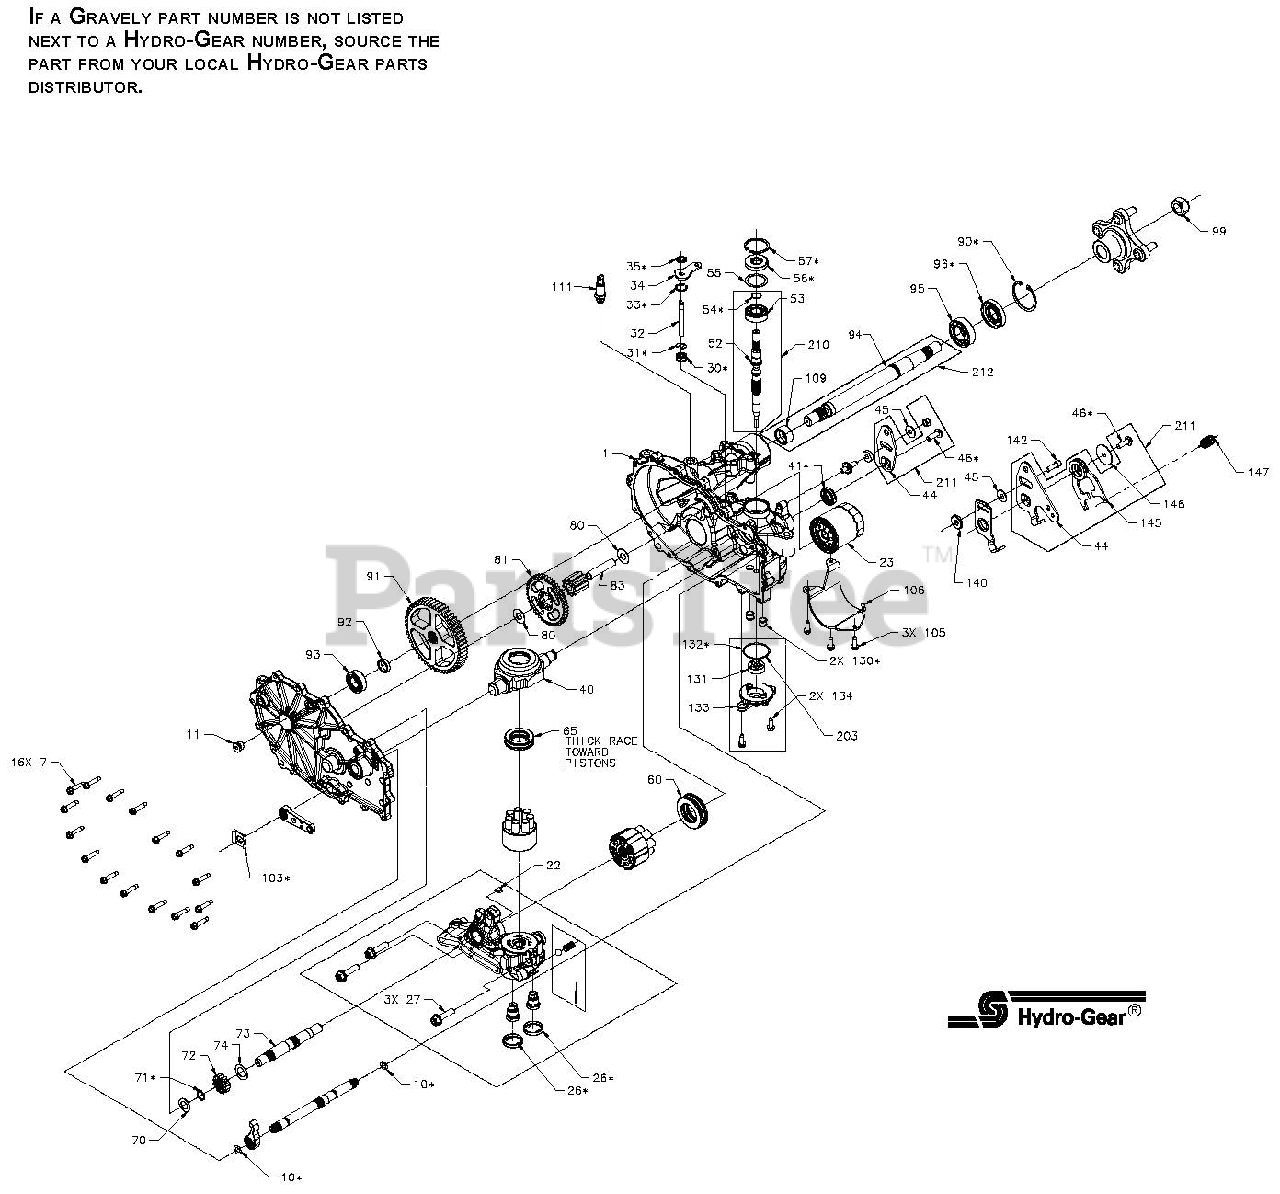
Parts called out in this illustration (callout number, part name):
1	Kit, Main Housing LH
7	HFHCS 1/4-20 x 1.25
10	O-Ring, 111 .103 x .424
11	Plug, 9/16-18
22	Plate, Bypass
23	Filter, Oil
26	Seal, Plug 1.25 x .25
27	HFHCS, 3/8-16 x 1.5
30	Seal, Lip .375 x .75 x .25
31	Ring, Retention .375 External
32	Rod, Bypass
33	Ring, Retention .750 Internal
34	Arm, Bypass
35	Ring, Retention .375 Ext
40	Trunnion, Swashplate
45	Washer, .34 x .88 x .06
46	TWHCS 5/16-24 x 1.00
52	Shaft, Input
53	Bearing, Ball 17 x 40 x 12 Open 6203
54	Ring, Ret Wire .561 ID
55	Washer, 1.23 x 1.56 x .04
56	Seal, Lip 17 x 40 x 7
57	Ring, Ret 1.59 Int
60	Bearing, Thrust
65	Bearing, Thrust Ball 30 x 52 x 13
70	Washer, .63 x 1.0 x .05
71	Ring, Retaining .625
72	Gear, 13T, Steel
73	Shaft, Motor
74	Washer, .72 x 1.16 x .04
80	Washer, .5 x 1.0 x .03
81	Gear, 46T
83	Jack Shaft
90	Ring, Ret 2.06 Int
91	Gear, 54T
92	Spacer, .75 x 1.0 x .257
93	Bearing, Ball .75 x 40 x 12
95	Bearing, Ball 1.0 x 52 x 15 Open 6205M
96	Seal, Lip 25 x 52 x 10 TC
99	Nut, Hex Lock 3/4-16
103	Clip, Retaining
105	HFHCS 1/4-20 x .75
106	Guard, Filter, LH
111	Fitting, Str 9/16-18 SAE .5 Barb
130	Tube, Connecting
131	Assembly, Gerotor Tang x 1.15 x .39
132	O-Ring, -137, 0.103 x 2.05
133	Cover, Charge Pump
134	HFHCS 1/4-20 x .75
140	Spacer, .320 x 1.00 x .179
142	SHCS 5/16-24 x 1 Patch
146	Washer, .343 x 1.5 x .062
147	Spring, Extension Rtn - 34 lbs
200	Kit, Seal
203	Kit, Charge Pump
210	Kit, Input Shaft
211	Kit, Rtn CCW
212	Kit, Axle Shaft
NS	Sealant
NS	15W50 Synthetic Motor Oil
